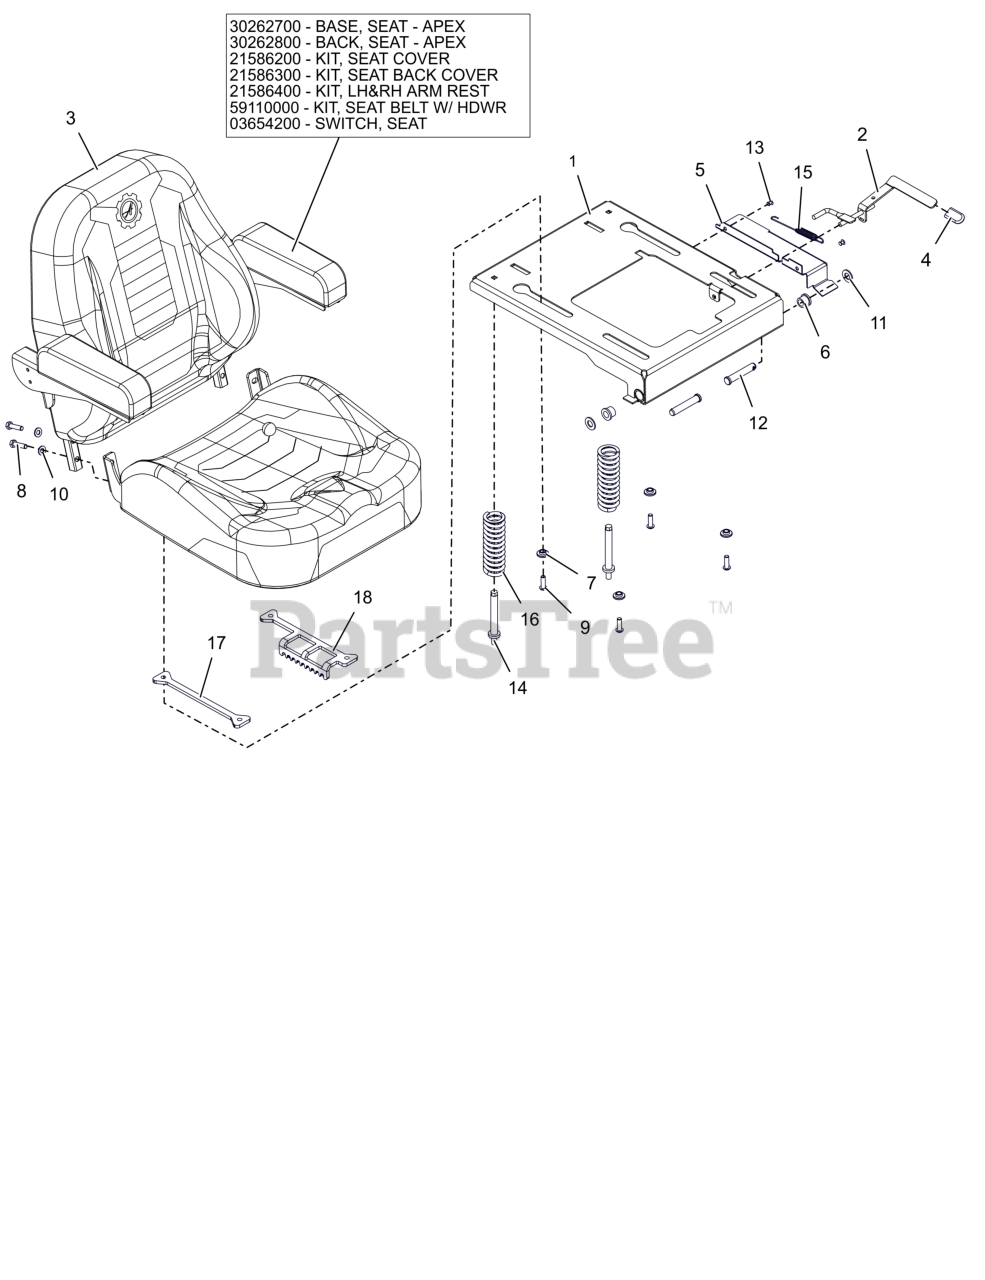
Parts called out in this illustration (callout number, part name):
1	WLDMT, SEAT PLATE HD
2	WLDMT, SEAT SLIDE LEVER
3	SEAT, ASM APEX/ZENITH
3	BASE, SEAT - APEX
3	BACK, SEAT - APEX
3	KIT, SEAT COVER BOTTOM
3	KIT, SEAT BACK COVER
3	KIT, LH & RH ARM REST
3	KIT-SEAT BELT REPLACE-05007300
3	SWITCH- SEAT
4	GRIP, SEAT LEVER, GREY
5	GUARD, SEAT PLATE CE
6	BSHG, FLG .516X.750X.625X.937
7	BSHG-FLG .325X.499X.3X.875
8	BLT, HEX .31-18X1.25 G5 ZCC
9	BLT,SHCS-BTN .31-18X1.00 ZCC
10	WSHR,FLT .344X.688X.065 ZCC
11	WSHR-FL-NYL .518X1.000X.080
12	PIN-CLIC .50X2.70X2.31 -ZCC
13	RVT-POP .187x.250 (#64) BLK
14	BOLT, SEAT SPRING
15	SG-TENS .06X.482X5.35
16	SPRING, COMPRESSION SEAT 224LB
17	PLATE, ADJUSTABLE
18	PLATE, HD SEAT ADJUSTMENT
